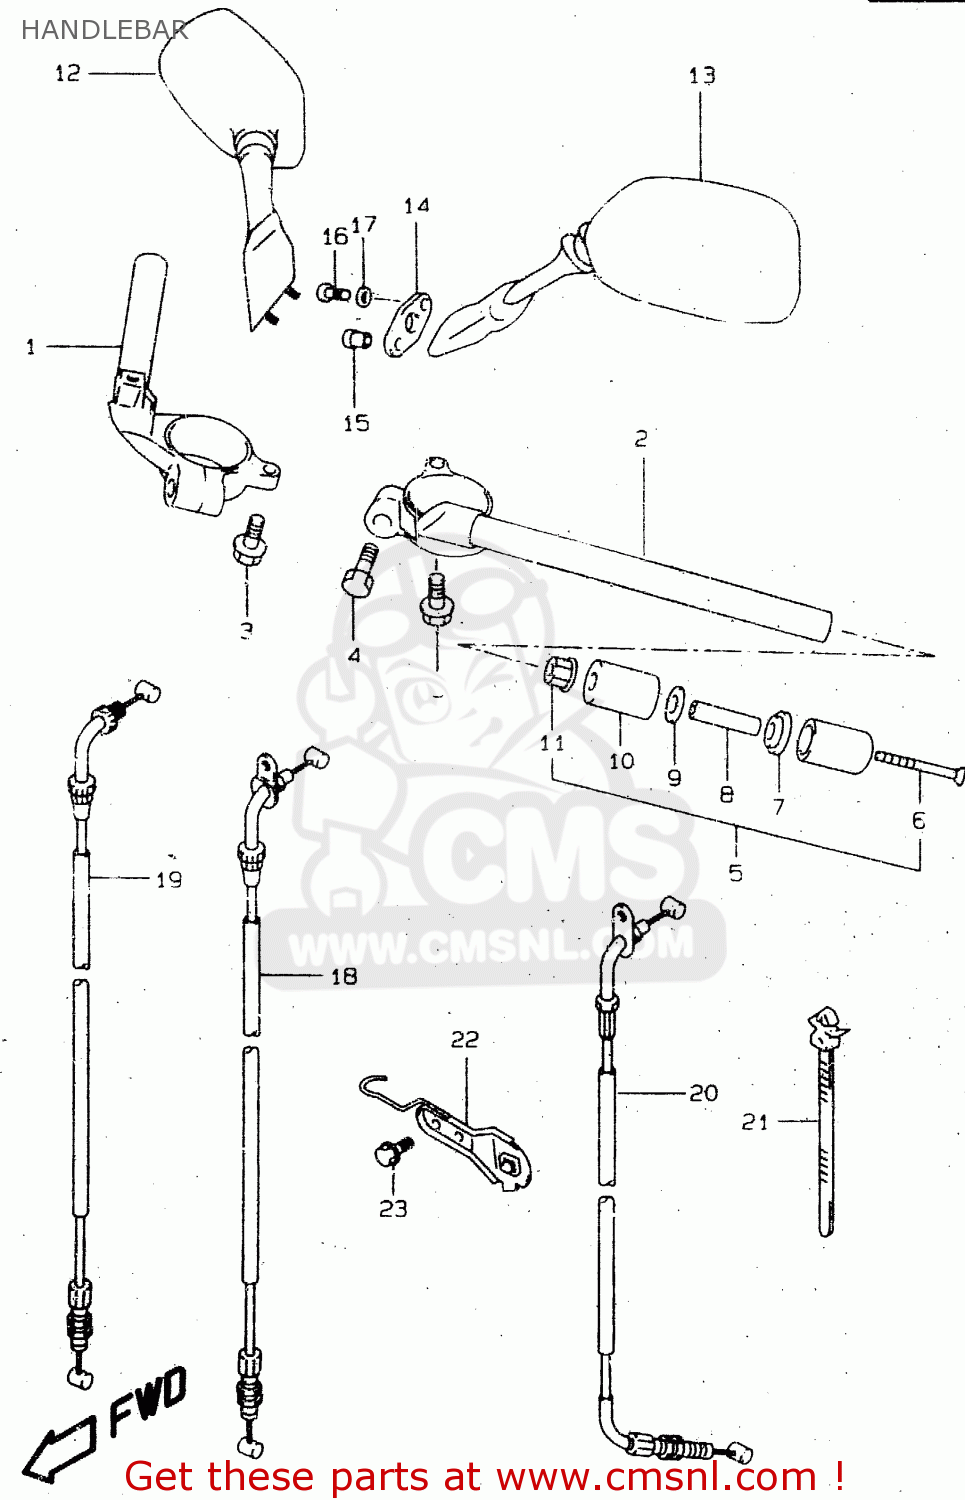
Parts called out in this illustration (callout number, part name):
1	HANDLEBAR,R
2	HANDLEBAR,L
3	BOLT
4	BOLT(8X30)
5	BALANCER SET,HANDLEBAR
6	SCREW(6X110)
7	EXPANDER,HANDLE BALANCER
8	SPACER,EXPANDER
9	WASHER(6.5X14X2)
10	EXPANDER,HANDLE BALANCER
11	NUT
12	MIRROR ASSY,RR VIEW,R
13	MIRROR ASSY,RR VIEW,L
14	CUSHION,RR VIEW MIRRORR
15	NUT,RR VIEW MIRROR
16	SCREW(6X12)
17	WASHER(6.2X19X1.5)
18	CABLE ASSY,THROTTLE NO.1
19	CABLE ASSY,THROTTLE NO.2
20	CABLE,STARTER
21	CLAMP(L:165)
22	GUIDE,CABLE
23	BOLT
